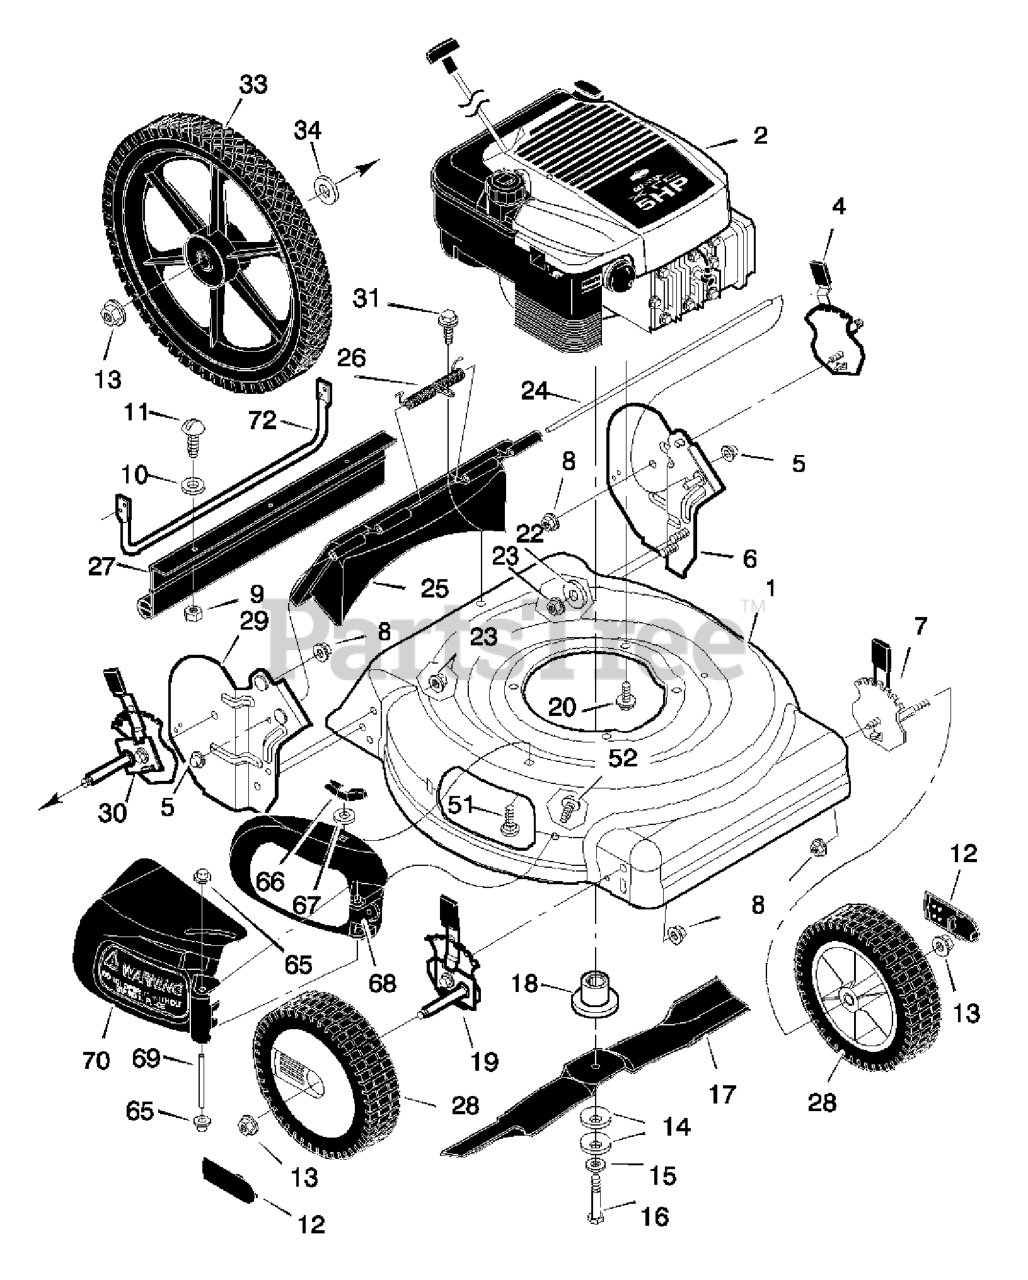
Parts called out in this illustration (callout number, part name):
1	Housing
2	Engine *
4	Adjuster, Left Height
5	Push On Cap
6	Bracket, Left Handle
7	Adjuster, Left Front Height
8	Nut, Flange
9	Nut, Hex
12	Hub Cap
13	Nut, Flange
14	Washer, Belleville
18	Adapter, Blade
19	Adjuster, Right Front Height
20	Bolt, Engine
22	Washer
23	Nut, Flange
24	Rod, Pivot
25	Door, Rear
27	Guard, Rear
28	Wheel
29	Bracket, Right Handle
30	Adjuster, Right Height
33	Wheel, Rear
34	Washer
51	BOLT, Carriage
65	Push On Cap
66	Wingnut
67	Retainer, Push
69	Pin, Pivot
70	Deflector, Chute
